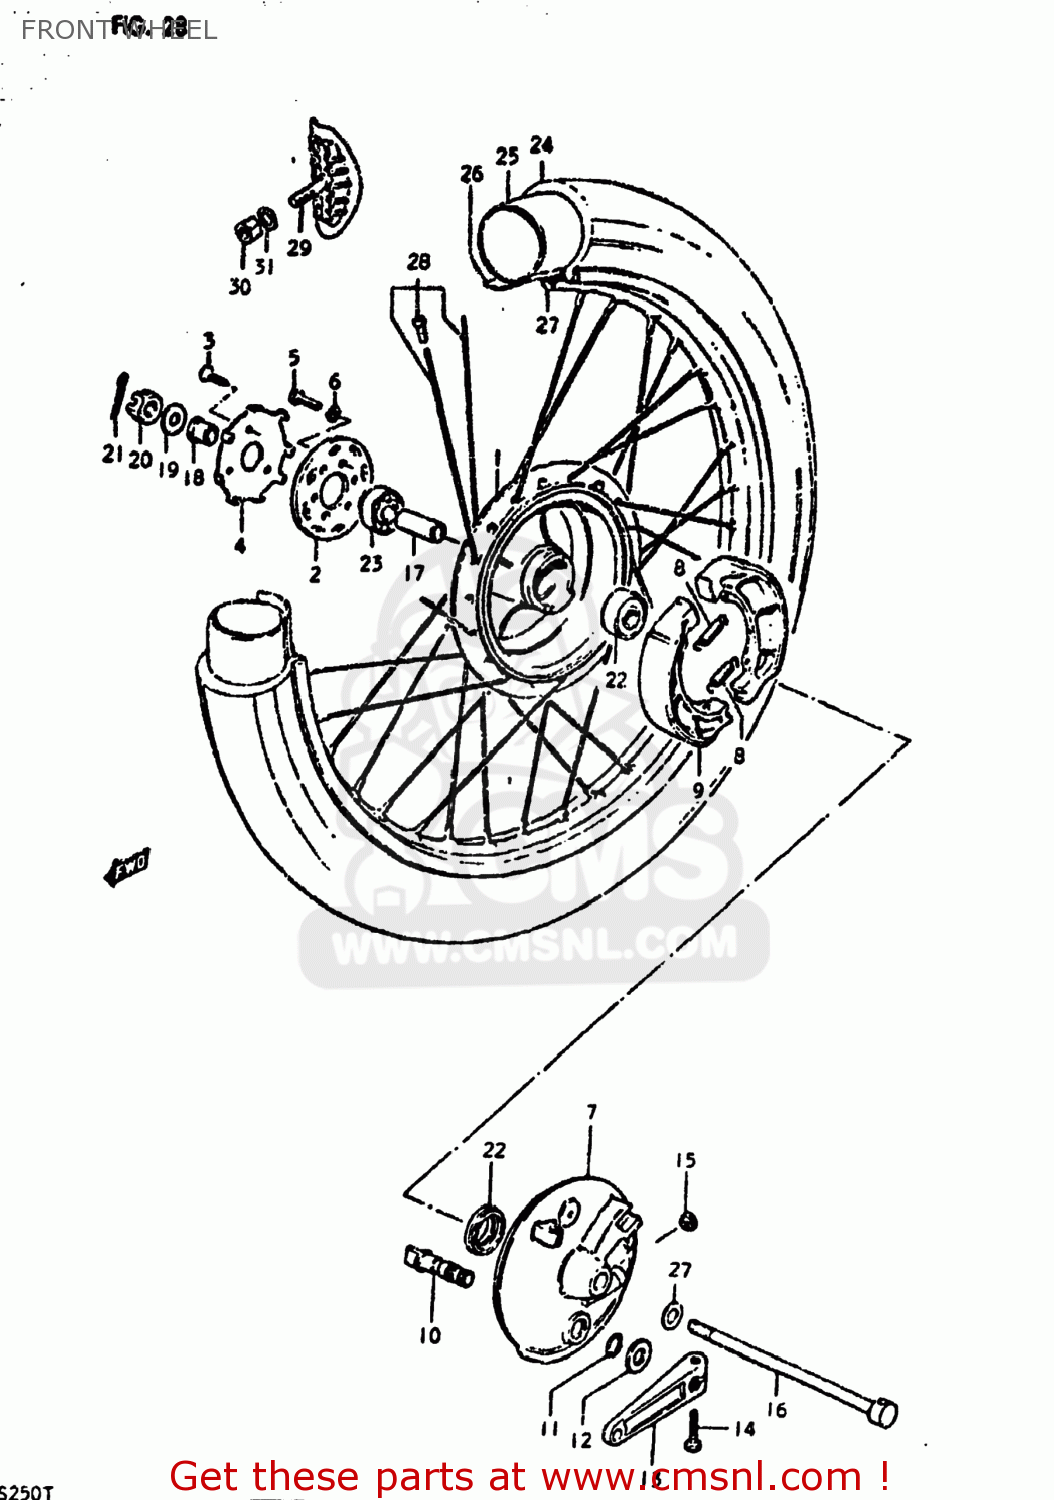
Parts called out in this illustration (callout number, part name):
1	DRUM,FRONT HUB
2	FLANGE,FR HUB,R
3	SCREW
4	RETAINER,FR HUB BEARING,R
5	BOLT, UPPER
6	LOCK WASHER
7	PANEL,FRONT HUB
8	SHOE,BRAKE (MCA)
9	SPRING
10	CAM,FRONT BRAKE
11	O-RING,BOSS
12	WASHER (15X24X1.6)
13	LEVER,FRONT BRAKE CAM
14	BOLT
15	PLUG(OD:19)
16	AXLE,REAR
17	SPACER (12.6X19X52)
18	SPACER,FR AXLE,R
19	WASHER
20	NUT, REAR AXLE
21	COTTER PIN
22	BEARING
23	BEARING, RH
24	TIRE,FRONT
25	TUBE,INNER
26	PROTECTOR,WHEEL,INNER
27	RIM,FRONT WHEEL
28	SPOKE SET,FR
29	STOPPER,BEAD
30	NUT
31	WASHER
